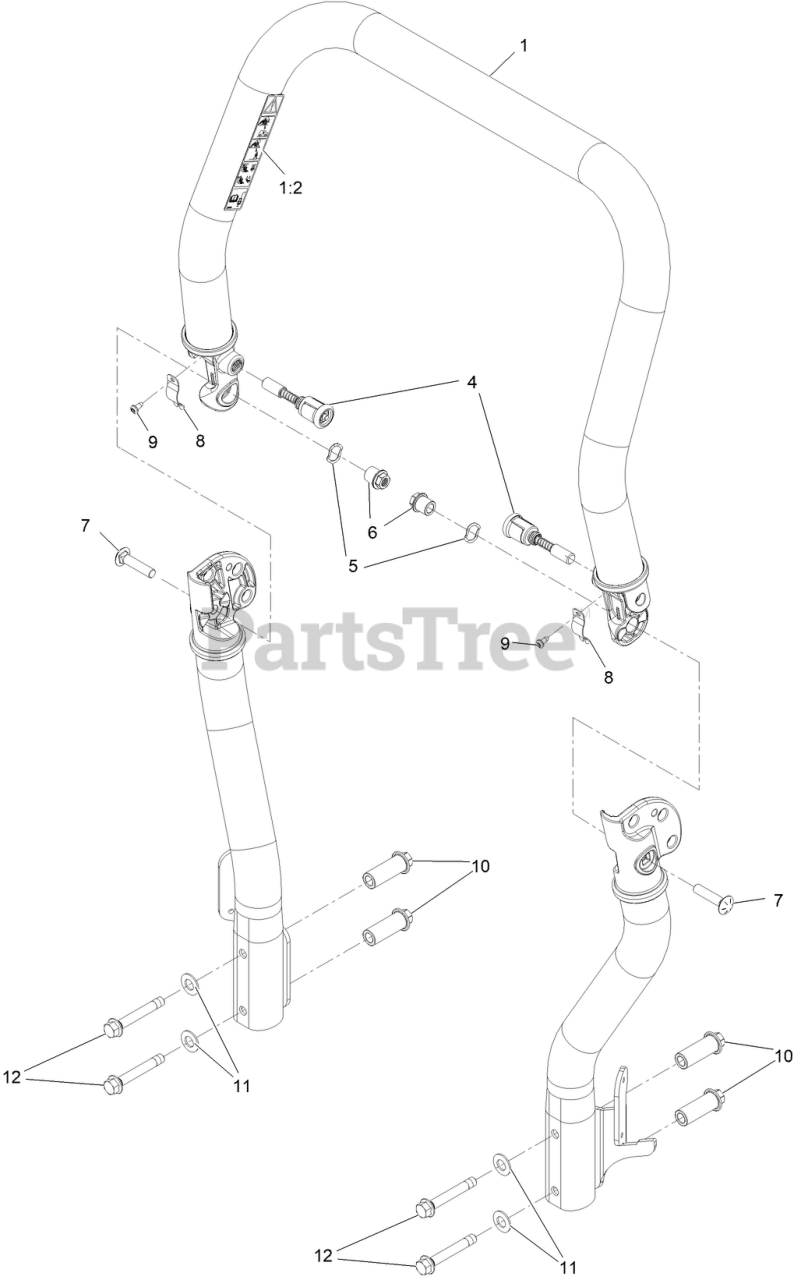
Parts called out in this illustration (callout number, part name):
1	ASM, ROPS Upper W/ Decal
1:2	DECAL-WARNING
4	PIN-SPRING
5	WASHER, WAVE
6	Nut, ROPS Pivot
7	Bolt,CARR, Spcl
8	SPRING, LEAF
10	SPACER, ROPS
11	Bolt, Shoulder
12	WASHER, BELLEVILLE
